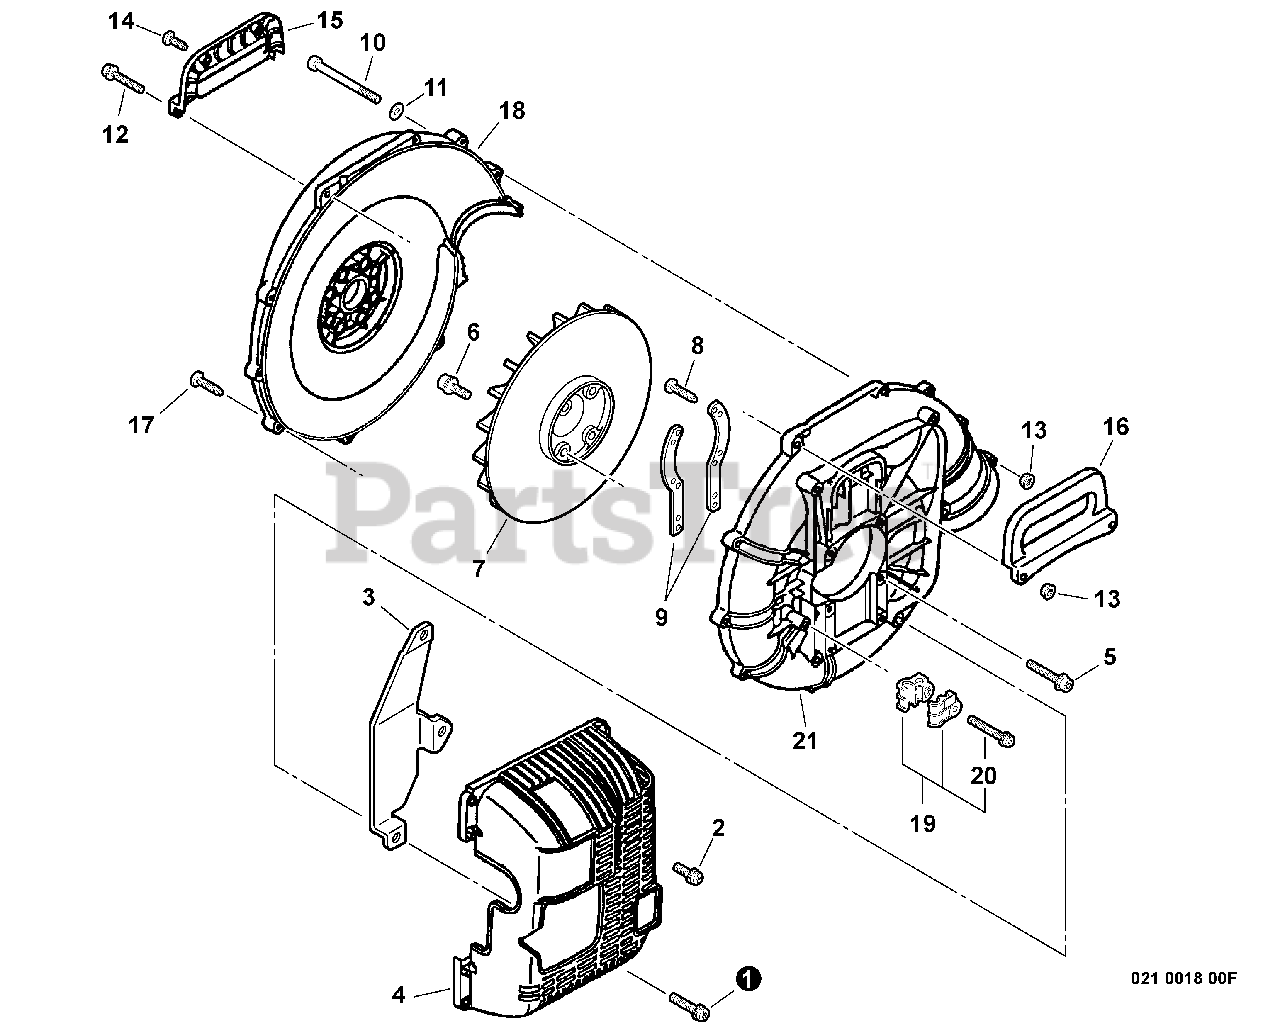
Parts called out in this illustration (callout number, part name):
1	SCREW - 5X18
2	SCREW - 5X10
3	INSULATOR
4	COVER, ENGINE
5	SCREW - 5X32
6	SCREW - 5X20
8	SCREW - 3X12 -- TAPPING
9	BRACKET, ENGINE
10	SCREW - 5X60
11	WASHER - 5
12	SCREW - 5X45
13	NUT - 5 -- FLANGE
14	SCREW - 5X16 -- TAPPING
15	HANDLE - INNER -- GRAY
16	HANDLE - OUTER -- GRAY
17	SCREW - 5X30
18	COVER, FAN - INNER -- GRAY
19	CABLE HOLDER KIT
20	SCREW - 5X25
21	COVER, FAN - OUTER
